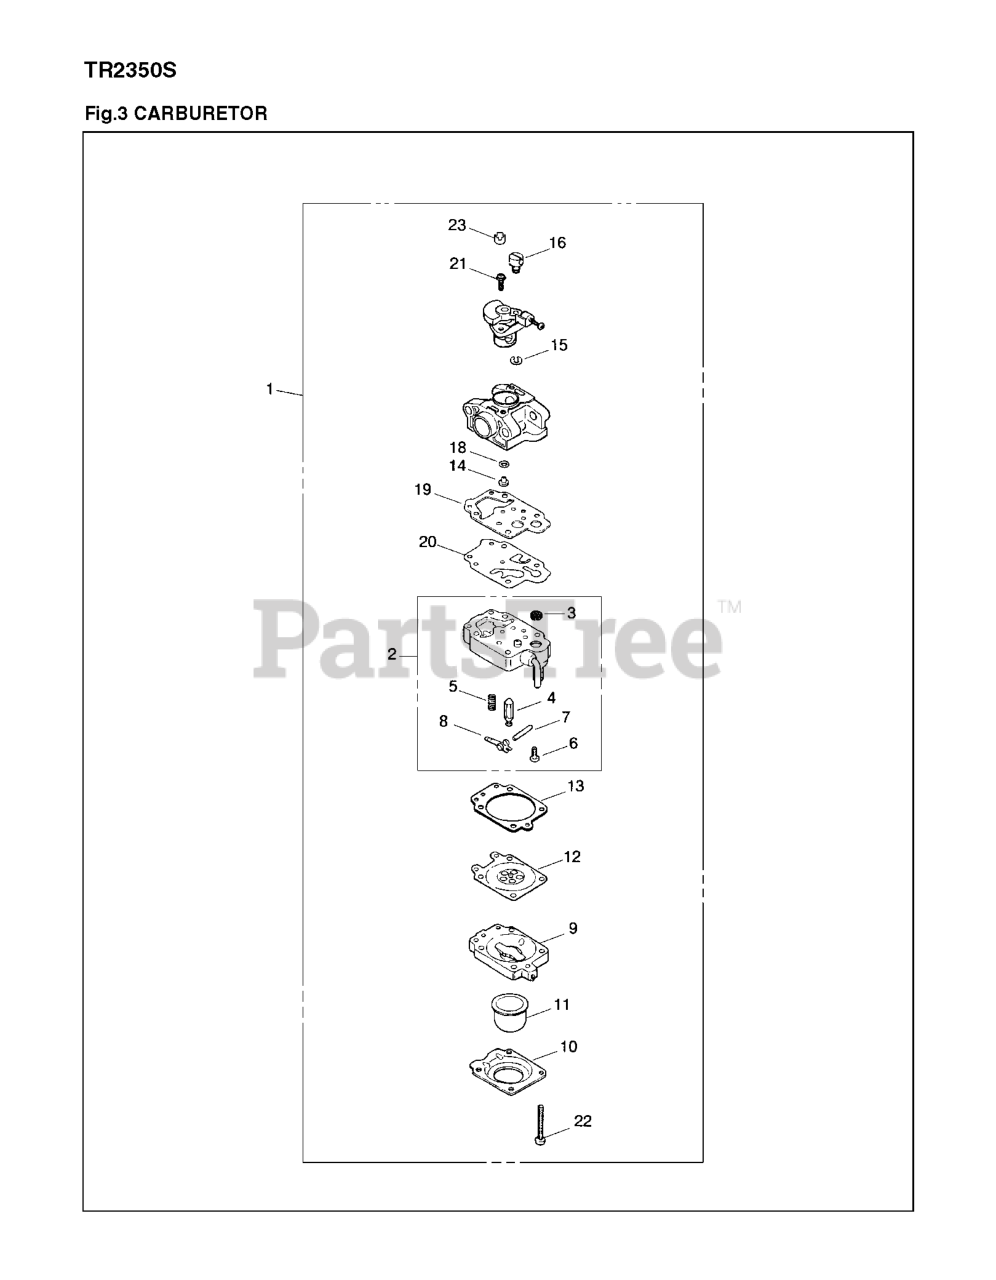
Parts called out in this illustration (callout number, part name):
1	CARBURETOR-A
3	SCREEN
4	VALVE INLET
10	1OVER
15	RING
16	SWIVEL
20	DIAPHRAGM
23	HI-SPEED NEEDLECAP 20-PK
